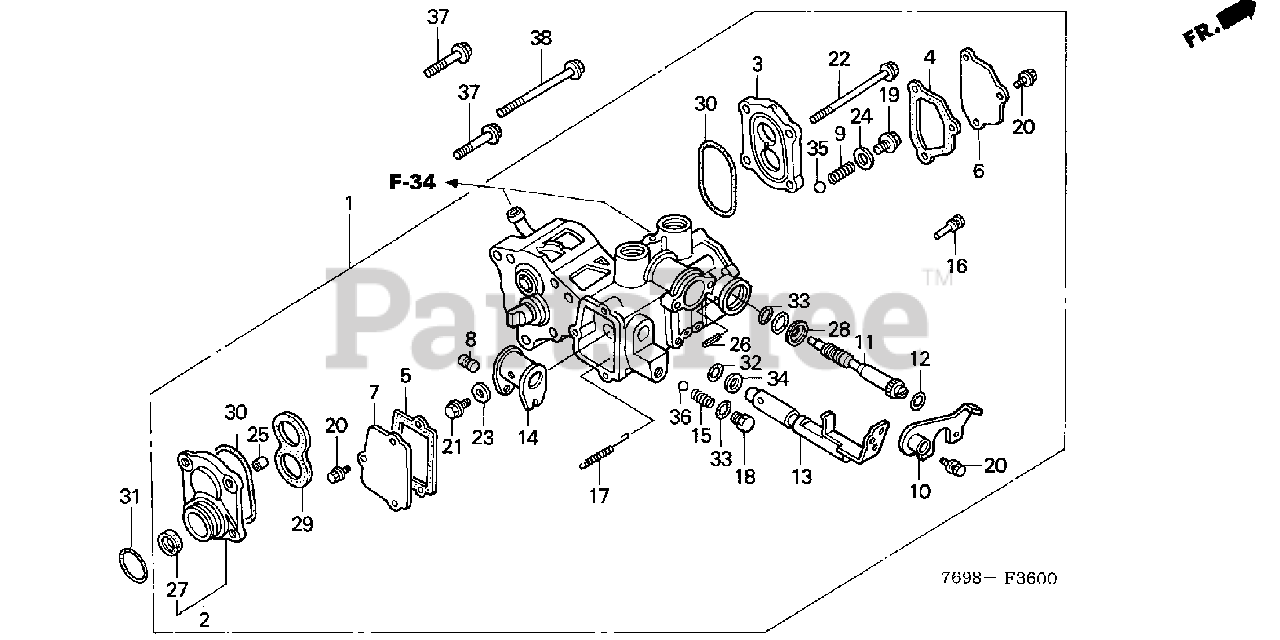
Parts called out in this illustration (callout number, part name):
1	PUMP & VALVE ASSY.
2	COVER, FR. PUMP
3	COVER, RR.
4	GASKET A, VALVE FRAME
5	GASKET B, VALVE FRAME
6	COVER A, VALVE FRAME
7	COVER B, VALVE FRAME
8	PIN, MANUAL VALVE
9	SPRING, ROTARY BALL SET
10	PLATE, ROTARY STOPPER
11	VALVE, DRAIN CONTROL
12	MARK, HYDRAULIC ADJUSTING KNOB (ENGLISH)
13	SHAFT, HYDRAULIC CONTROL
14	FORK, SPOOL VALVE
15	SPRING, BALL SET (A)
17	SPRING, MANUAL VALVE
18	PLUG (10X8.5)
19	BOLT, FLANGE (8X8)
20	BOLT, FLANGE (6X14)
21	BOLT, SPECIAL (6X20)
22	BOLT, FLANGE (6X85)
23	WASHER, CONICAL SPRING (8MM)
24	WASHER, SEAL
25	PIN, DOWEL (8X10)
25	PIN A, DOWEL (8X10)
26	PIN, SPRING (4X20)
27	OIL SEAL (16X30X7) (NOK)
28	DUST SEAL (12X22X4)
29	SEAL, PLUNGER (NOK)
30	O-RING (53.8X3.1)
31	O-RING (37.5X2)
32	O-RING (11.8X2.4)
33	O-RING (7.8X1.9)
34	RING, BACK-UP (12MM)
35	BALL, STEEL (8)
36	BALL, STEEL (11)
37	BOLT, FLANGE (8X35)
38	BOLT, FLANGE (8X75)
